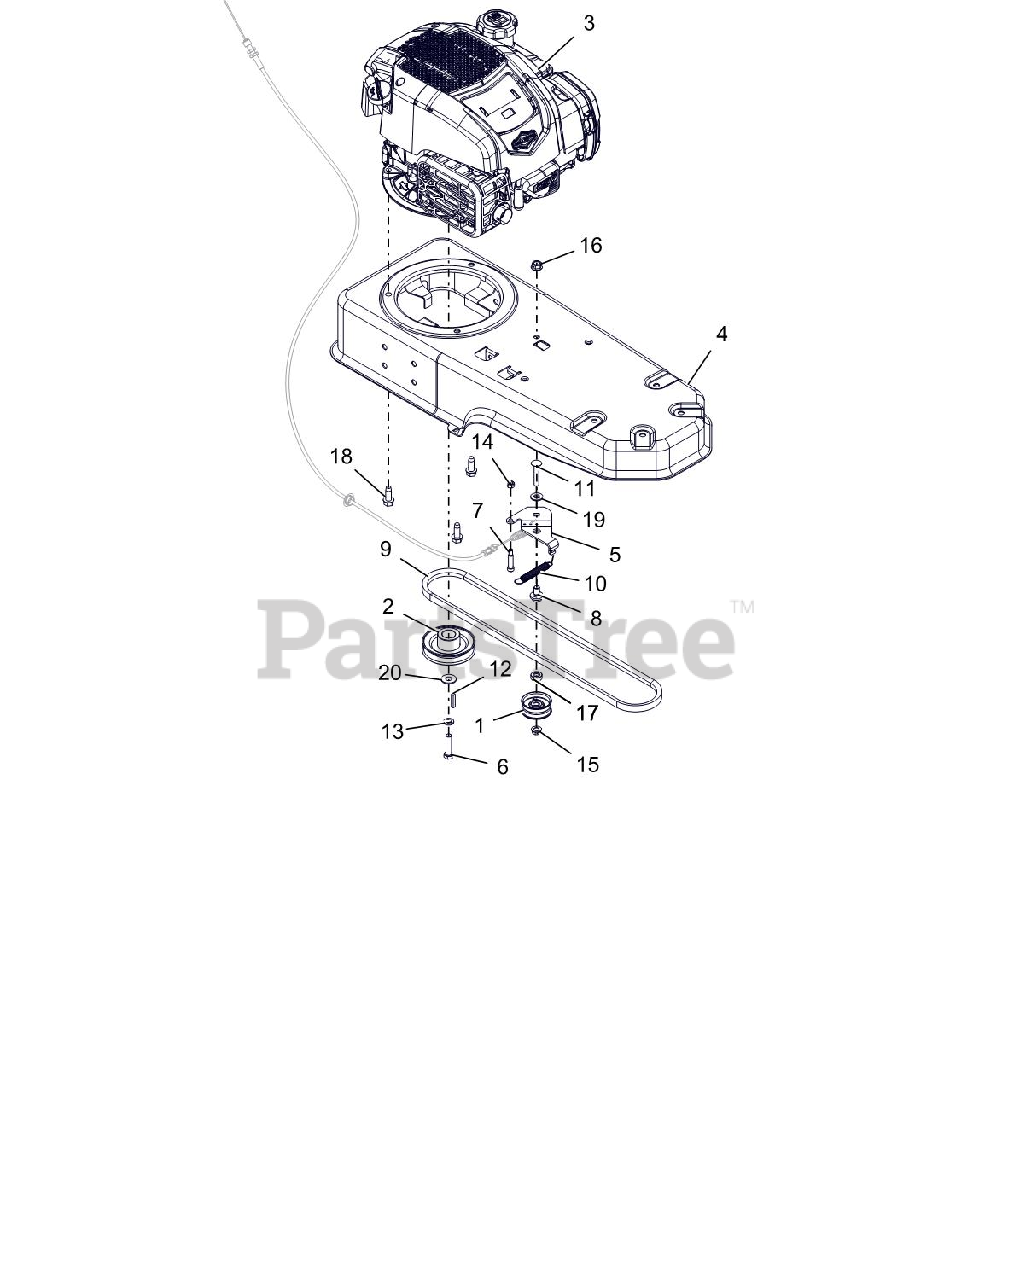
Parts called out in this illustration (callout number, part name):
1	IDLER, FLAT - 1.875"
2	WLDMT, DRIVE SHEAVE
3	ENGINE, B&S EXI 163CC CE
4	FRAME - TRIMMER
5	BRKT-IDLER STRING TRIMMER
6	BLT-HEX .38-24X1.50 HEX 8 YWZC
7	SCR-SHLDR .25-20X1.00 -YWZC
8	BOLT-SHLDR .375-16X.150
9	V-BELT, HA-RAW EDGE
10	SG-TENS .035X.45X2.75 WLD 3.5
11	BLT-RDHDSQSHK .31-18X1.75 YWZC
12	KEY-SQ .188X1.0X.188 SAE 8630
13	@WSHR-LK .38X.094 REG YWZC
14	@NUT-LK-CTR .25-20 YWZC
15	@NUT-LK-CTR-FLG .31-18 YZ GR F
16	NUT-LK-CTR-FLG .38-16 YWZC
17	SPCR, BRG .315X.500X.481X.281
18	@SCR-TAP .38-16X1.00 HWH TR YZ
19	WSHR-HDND .406X.812X.055
20	@WSHR-FL-STL.438X1.00X.083 YWZ
